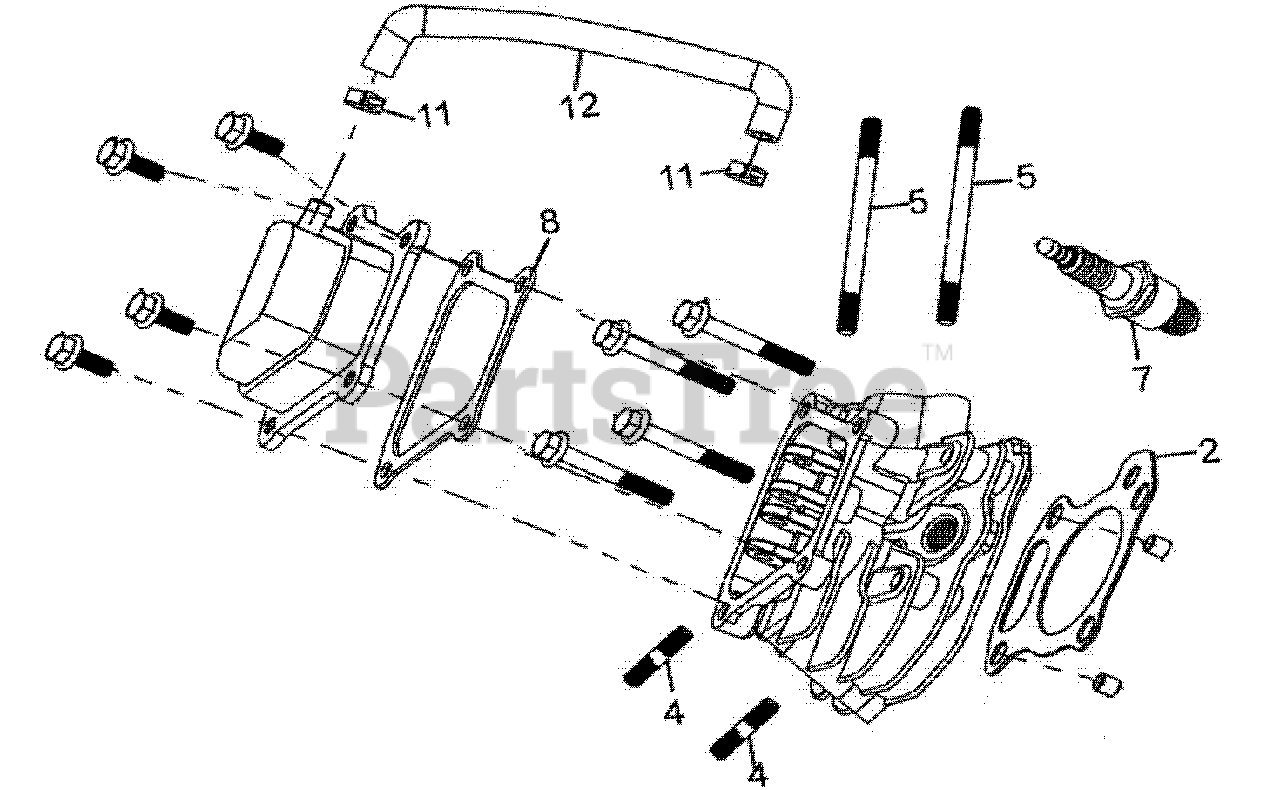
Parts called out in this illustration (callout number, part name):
2	GASKET,CYLINDER
4	BOLT ,STUD ,EXHAUST
5	BOLT ,STUD ,IN
7	SPARK PLUG E6TC
8	PACKING , HEAD COVER
11	LOOP,TUBE
12	TUBE,BREATHER
